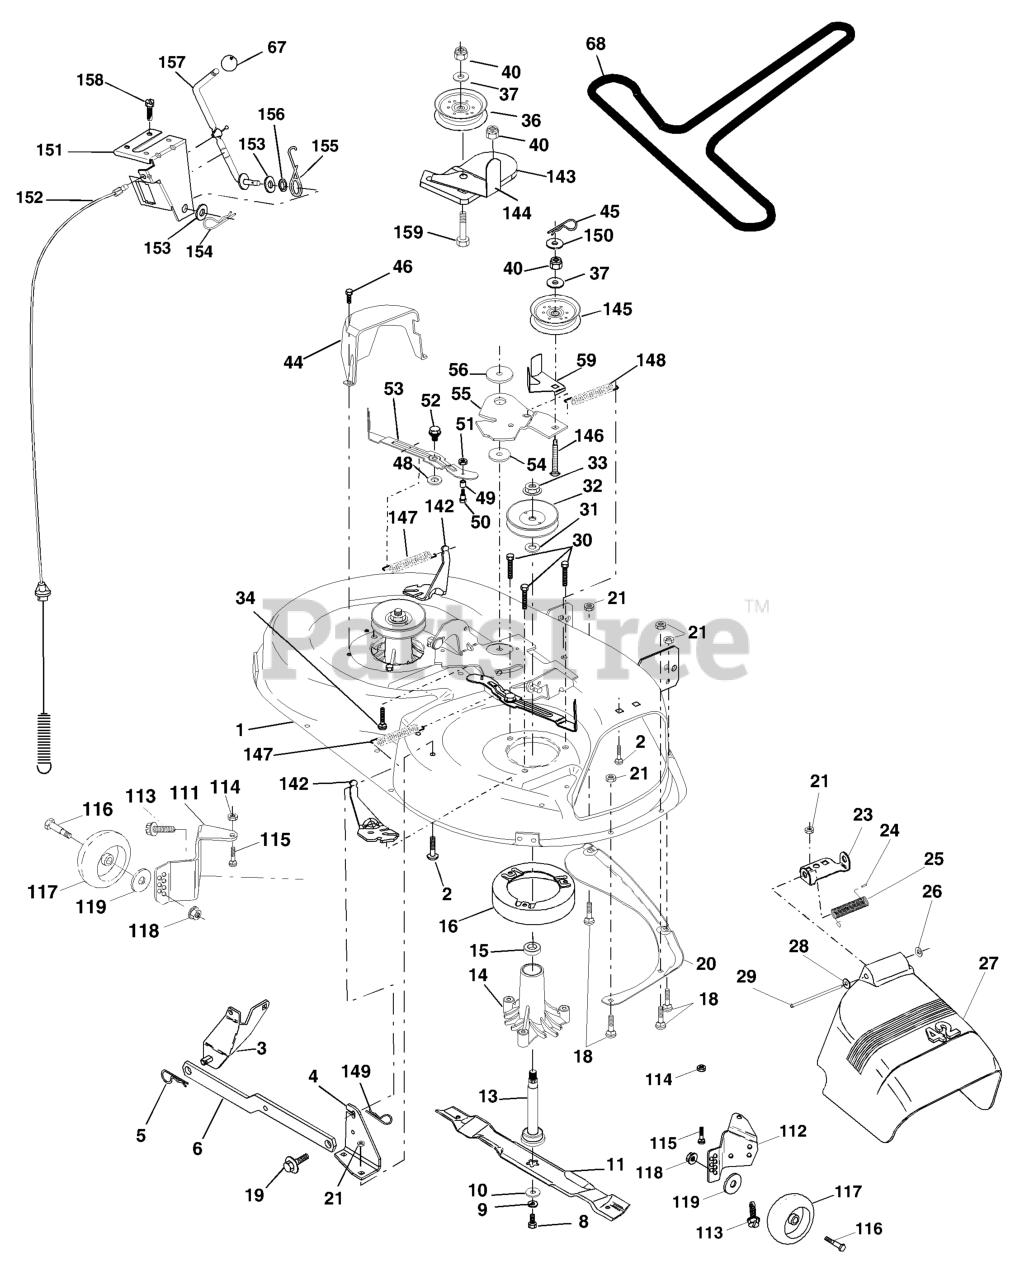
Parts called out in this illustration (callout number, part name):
1	DECK SVC 42"
2	RP BOLT 5/16-18 X3/4 ZN/YEL GR
3	BRKT ASM SWAY BAR
4	BRACKET SWAY BAR 42" DECK
5	RETAINER-SPRNG RB
6	BAR SWAY DECK
8	BLADE BOLT
9	LOCKWASHER
10	WASHER.BLADE
11	Blade Mower 42"
13	SHAFT ASM VENT
14	HOUSING.MANDREL.VENTED (MACHD)
16	STRIPPER.MANDREL.ROUND.BLACK
18	BOLT
19	BOLT SHD 5/16-18
20	BAFFLE.VORTEX
21	LOCKNUT
23	BRKT, DEFL. MOWER
24	CAP-SLEEVE LT
25	SPRING TORSION
26	NUT PUSH M
27	SHIELD DEFLECTOR
28	Washer 11/32 X 5/8 X 16 Ga
29	ROD.HINGE
30	SCREW, WASHER HEAD
31	WASHER
32	PULLEY MANDREL
33	NUT, FLG TOPLOCK 9/16"
36	PULLEY.IDLER.FLAT
37	WASHER
44	GUARD MANDREL LH BLACK
45	RETAINER M
46	SCREW.1/4-20X5/8
49	ROLLER ASM CAM FOLLOWER
52	BOLT.SHOULDER.5/16-18
53	ARM
54	HARDENED WASHER
55	ARM IDLER 42" MOWER LT/YT
56	SPACER RETAINER
59	GUARD TUV IDLER
67	KNOB T (3/8 HOLE)
68	BELT V SECONDARY
111	GUAGE WHEEL BRACKET LH
112	BRACKET WHEEL GUAGE KIT
113	Screw Tapping 3/8-16 x .625
114	NUT
115	BOLT.CARR.5/16-18X5/8.SHORT
116	BOLT M
117	WHEEL.GAUGE.STANDARD
118	LOCKNUT
119	WASHER.5/16.FLAT.STE.STD.
142	ARM SPRING BRAKE MOWER
143	BRACKET, ARM IDLER
144	KEEPER BELT 42" CLUTCH
145	PULLEY.IDLER.FLAT.PLATED
146	BOLT CARRIAGE IDLER
147	SPRING EXTENSION
148	IDLER RETURN SPRING
149	SPRING.RETAINER.YELLOW.ZINC
150	WASHER PM
151	BRACKET.CLUTCH.CABLE
152	CLUTCH CABLE 42"
153	WASHER FLAT 3/8"
154	SPRING RETAINER
155	SPRING RETENTION LEVER
156	SPACER.CLUTCH.CABLE
157	ROD CLUTCH CABLE 3/8"
158	SCREW
159	BOLT
